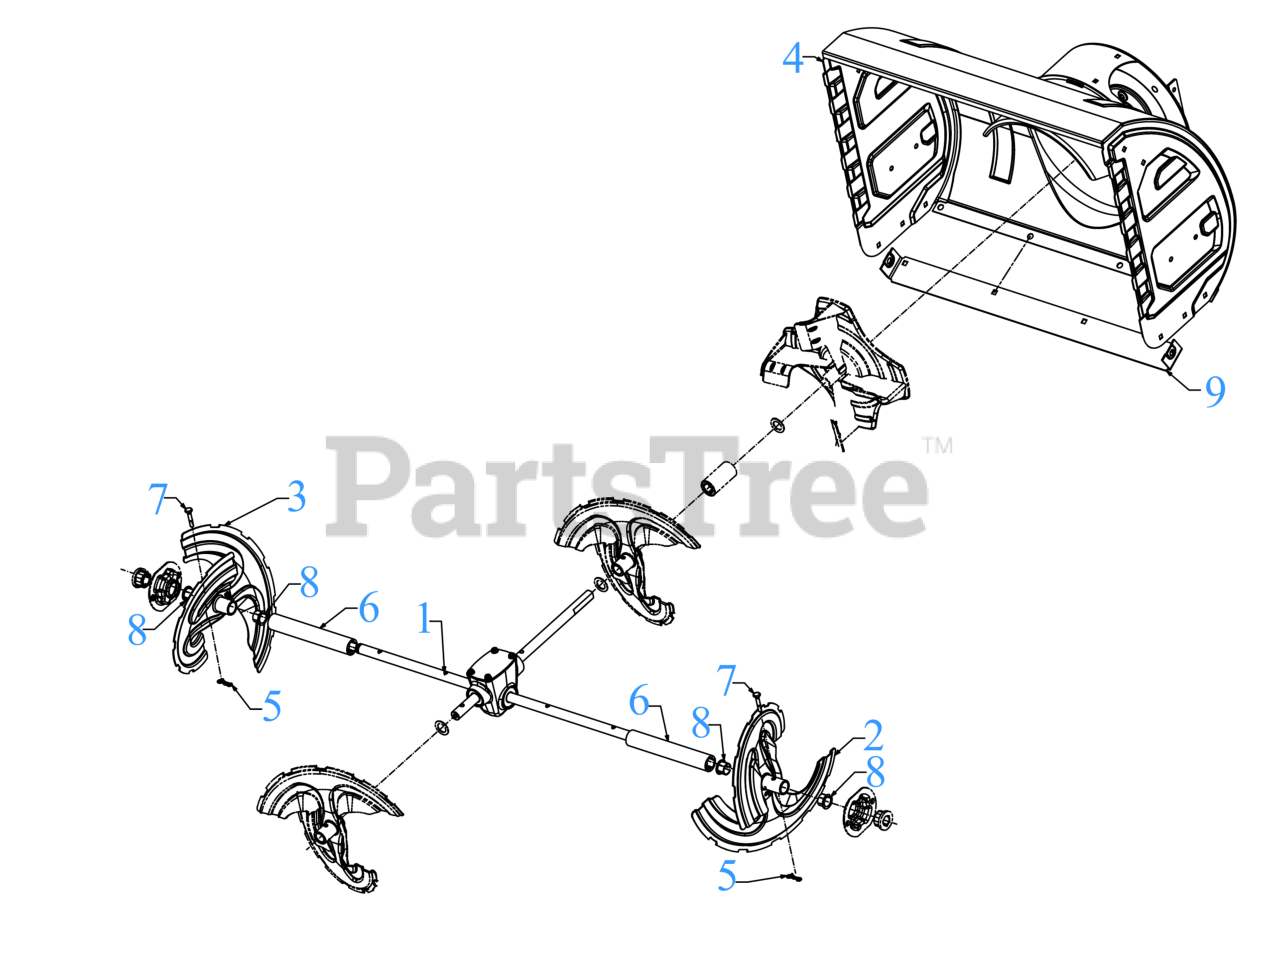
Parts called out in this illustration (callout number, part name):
1	GEARBOX ASSEMBLY 28"
5	BOW TIE COTTER PIN 1/4-5/16
7	SHEAR PIN (.25 x 1.50)
7	Cub Cadet SHEAR PINS (3X SNOW)
8	FLANGE BUSHING
